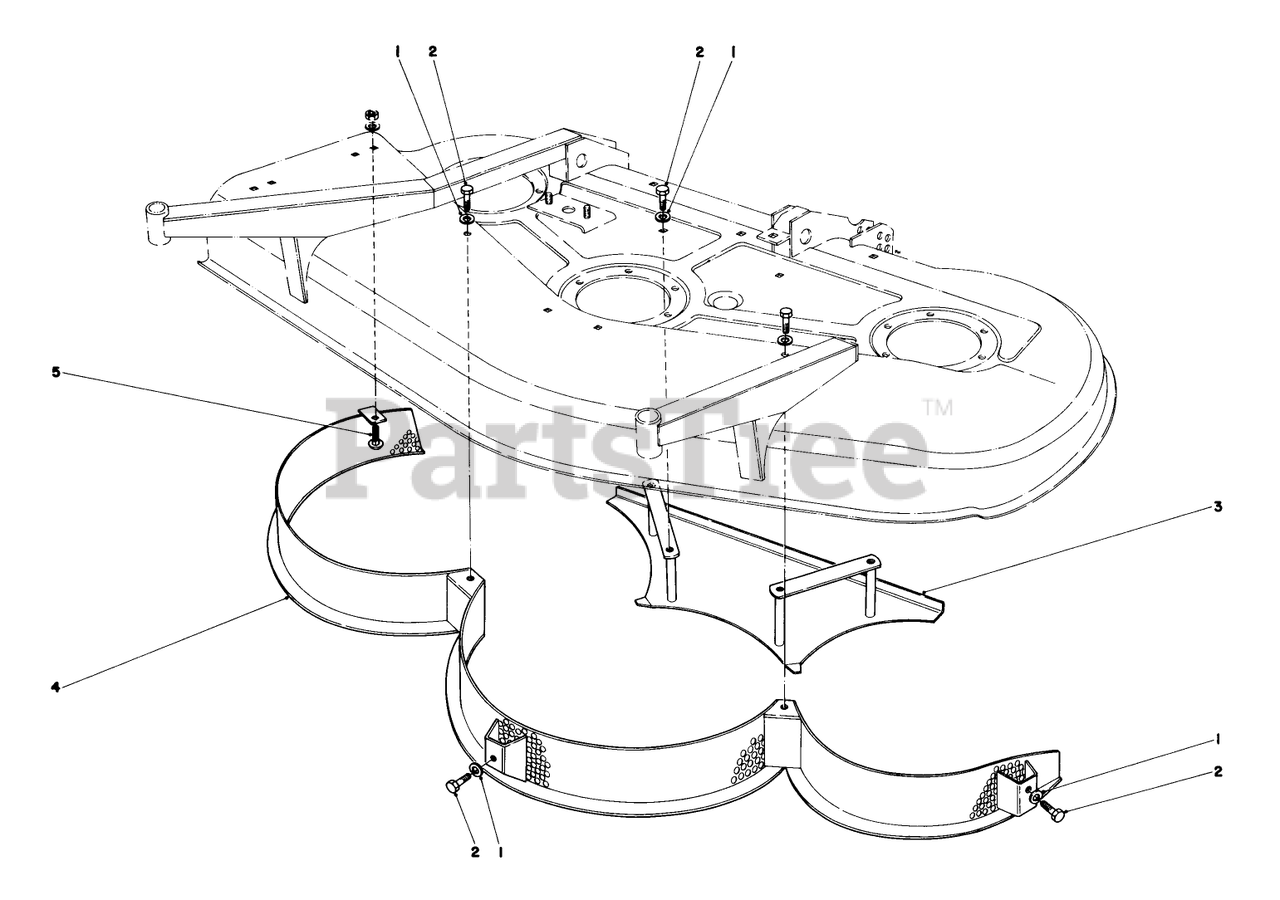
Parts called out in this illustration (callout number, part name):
1	WASHER-LOCK
2	SCREW-HH
3	Shelf Bottom Rear
4	Mulcher Screen
5	BOLT-CARR
